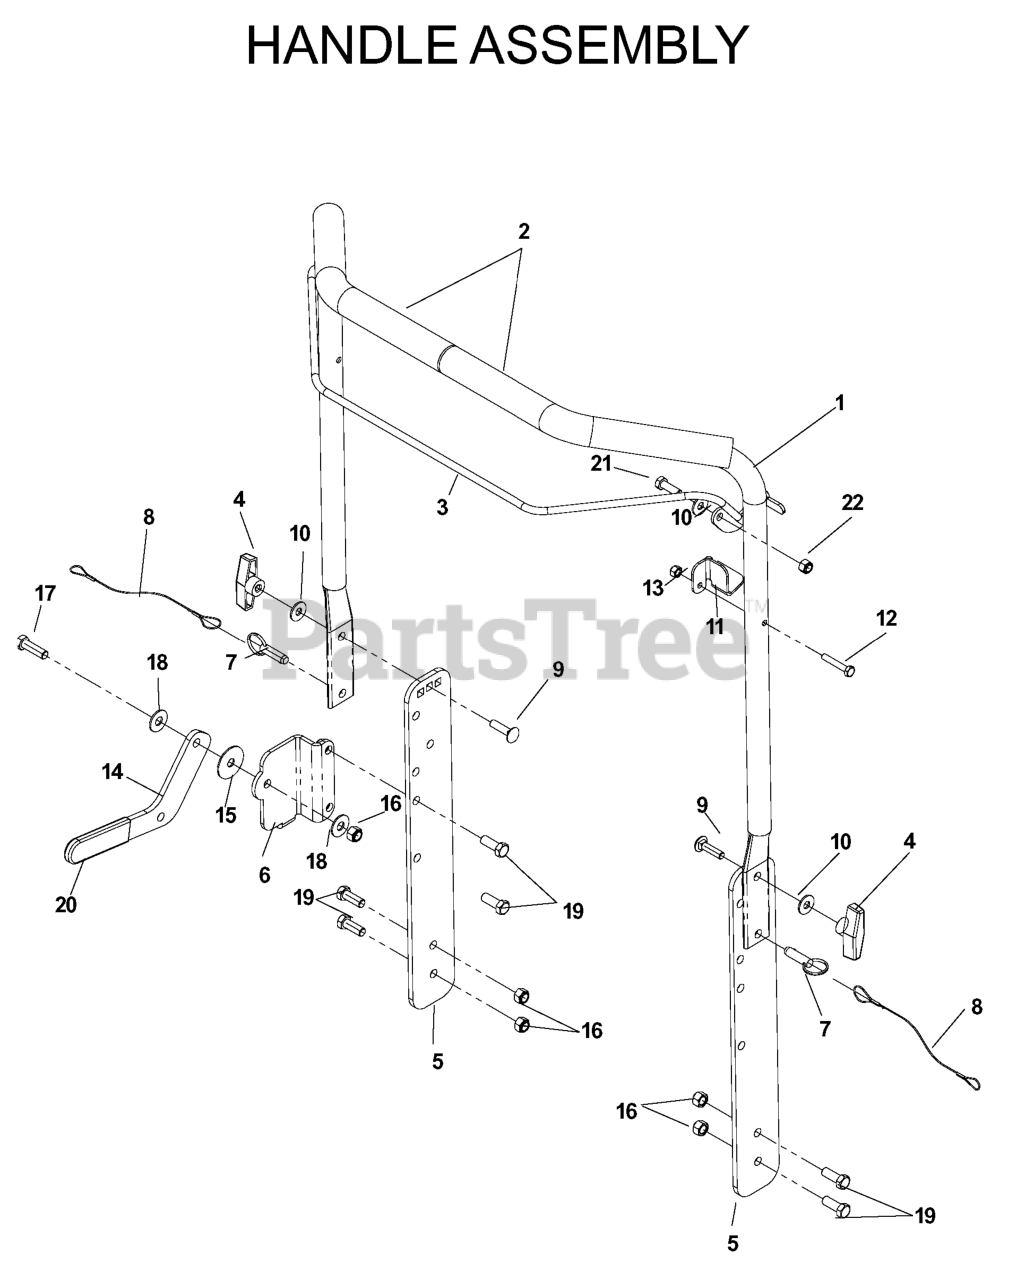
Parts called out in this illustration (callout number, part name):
1	HANDLE GRAY
3	BAIL - ORANGE
5	HANDLE SIDE GRAY
7	DETENT PIN RAKE/DT
9	BOLT, CARRIAGE 5/16X1-1/4
10	WASHER 5/16 FLAT
11	CABLE TAB POWER RAKE
12	SCW 1/4-20 X 1-1/2 HEX
13	NUT.1/4-20.HEX.NYLOC.ZD
15	WASHER, FRICTION
16	NUT 3/8-16 NYLOC
17	HCS 3/8C X 1 1/4 GR5
18	WASHER 3/8 FLAT
19	HCS 3/8-16X1.GRD.5.ZD
21	HCS 5/16C X 1
22	NUT 5/16 NYLOC
